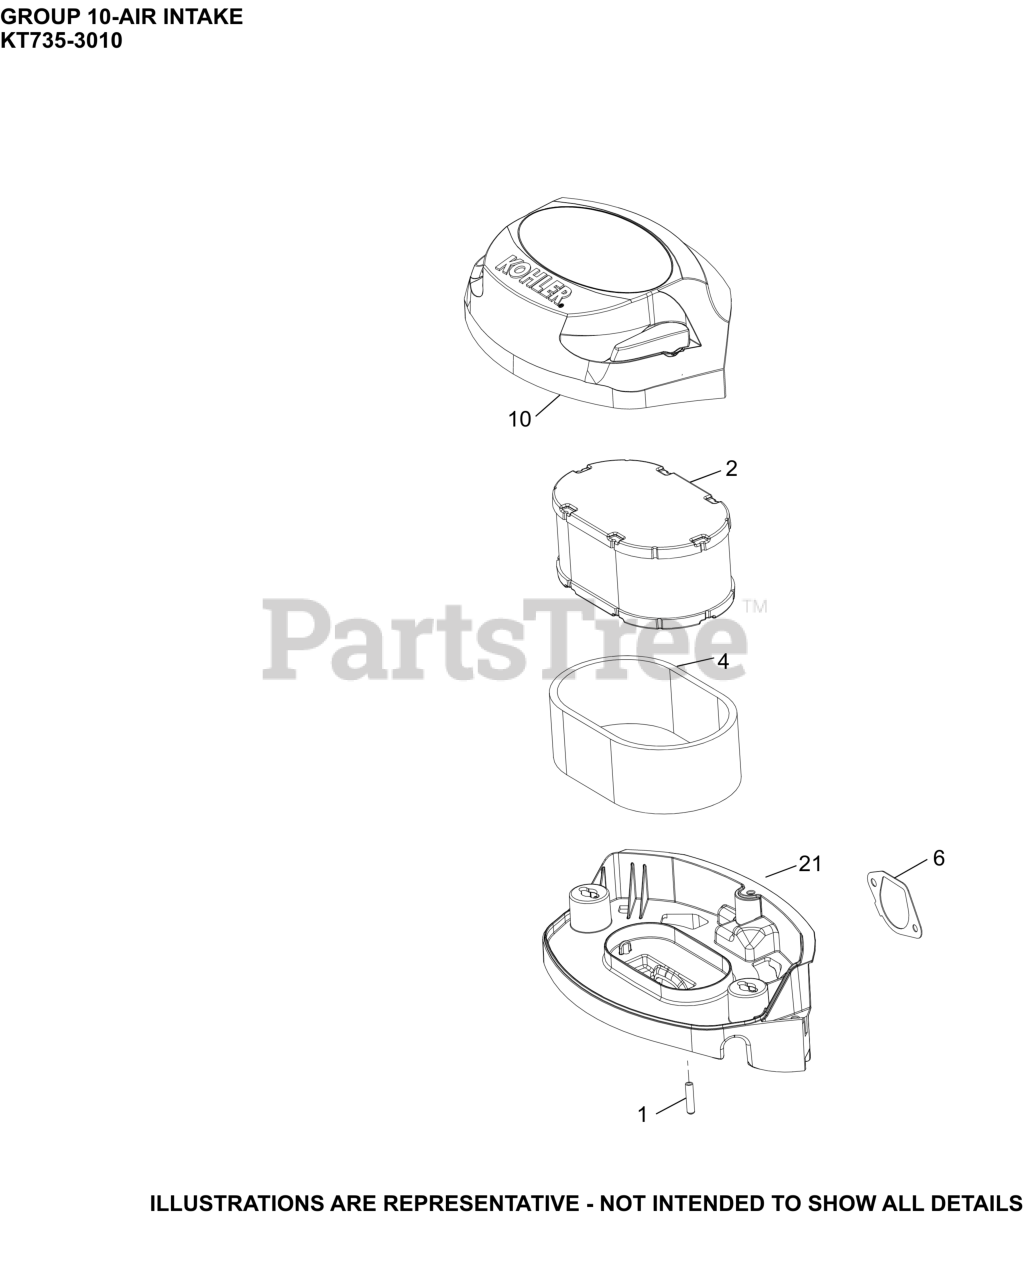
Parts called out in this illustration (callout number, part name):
1	CAP, MASKING
2	ELEMENT, AIR FILTER
4	ELEMENT, PRE-CLEANER
6	GASKET, AIR CLEANER BASE
10	COVER ASSY, AIR CLEANER
21	BASE ASSEMBLY, AIR CLEANER
